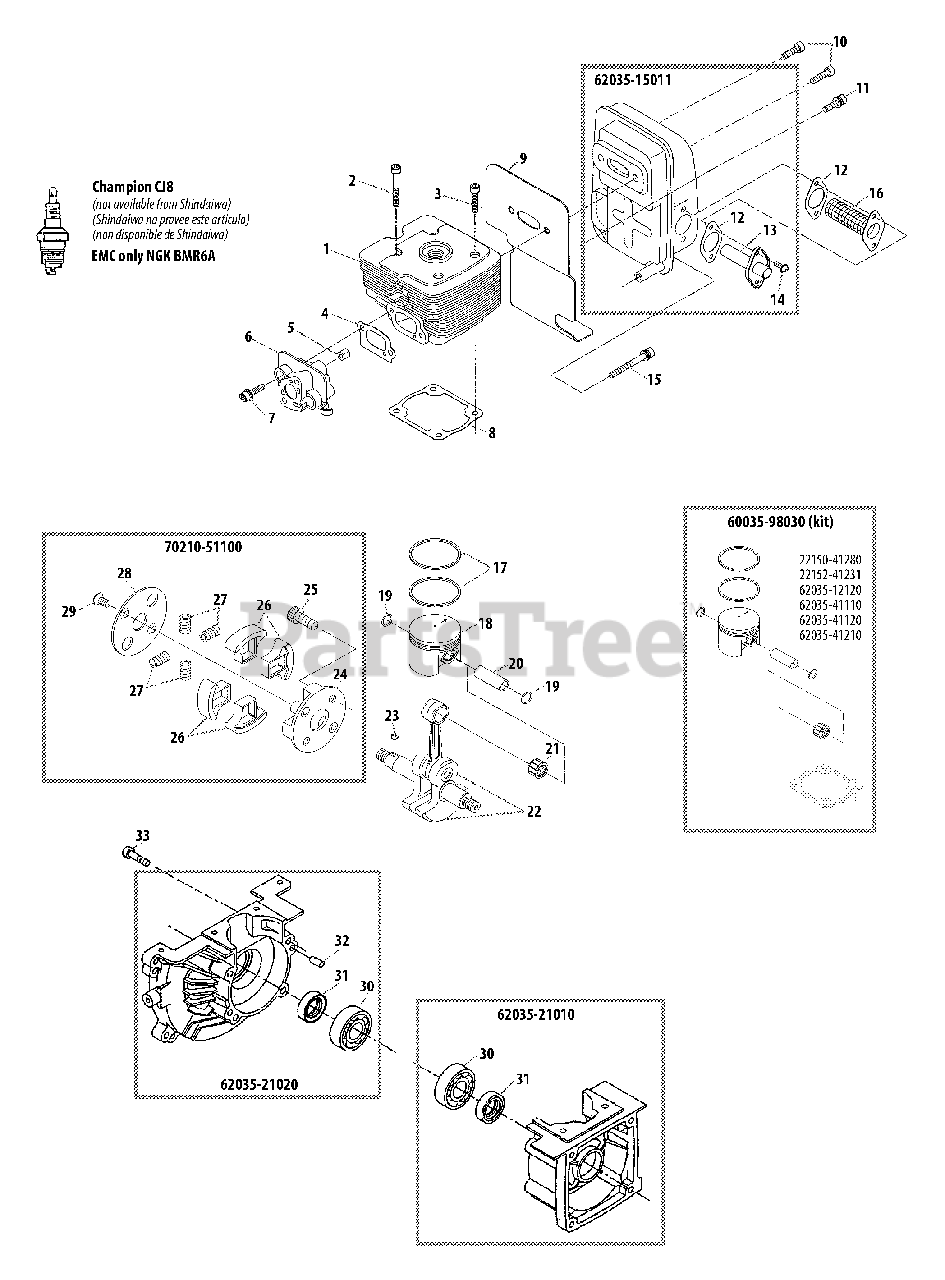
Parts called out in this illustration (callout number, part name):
1	CYLINDER
2	SCREW - 5X35
3	SCREW - 5X25
4	GASKET
5	NUT
6	INSULATOR
7	SCREW - 5X25
8	GASKET, CYLINDER
9	GASKET, EXHAUST
10	SCREW - 6X25
11	SCREW - 5X16
12	GASKET
13	TAIL PLATE
14	SCREW - 4X12
15	SCREW - 5X45
16	SCREEN, SPARK ARRESTOR
17	PISTON RING SET
18	PISTON
19	RING, RETAINING
20	PIN, PISTON
21	BEARING, NEEDLE
22	CRANKSHAFT ASSY
23	KEY - 3X10
24	HUB, CLUTCH
25	BOLT, CLUTCH
26	SHOE, CLUTCH
27	SPRING, CLUTCH
28	PLATE, CLUTCH
30	BEARING, BALL - 6202
31	SEAL, OIL
32	PIN - LOCATING
33	SCREW - 5X30
60035-98030	PISTON ASSY
62035-15011	MUFFLER ASSY
62035-21010	CRANKCASE ASSY - REAR
62035-21020	CRANKCASE ASSY - FRONT
70210-51100	CLUTCH ASSY
